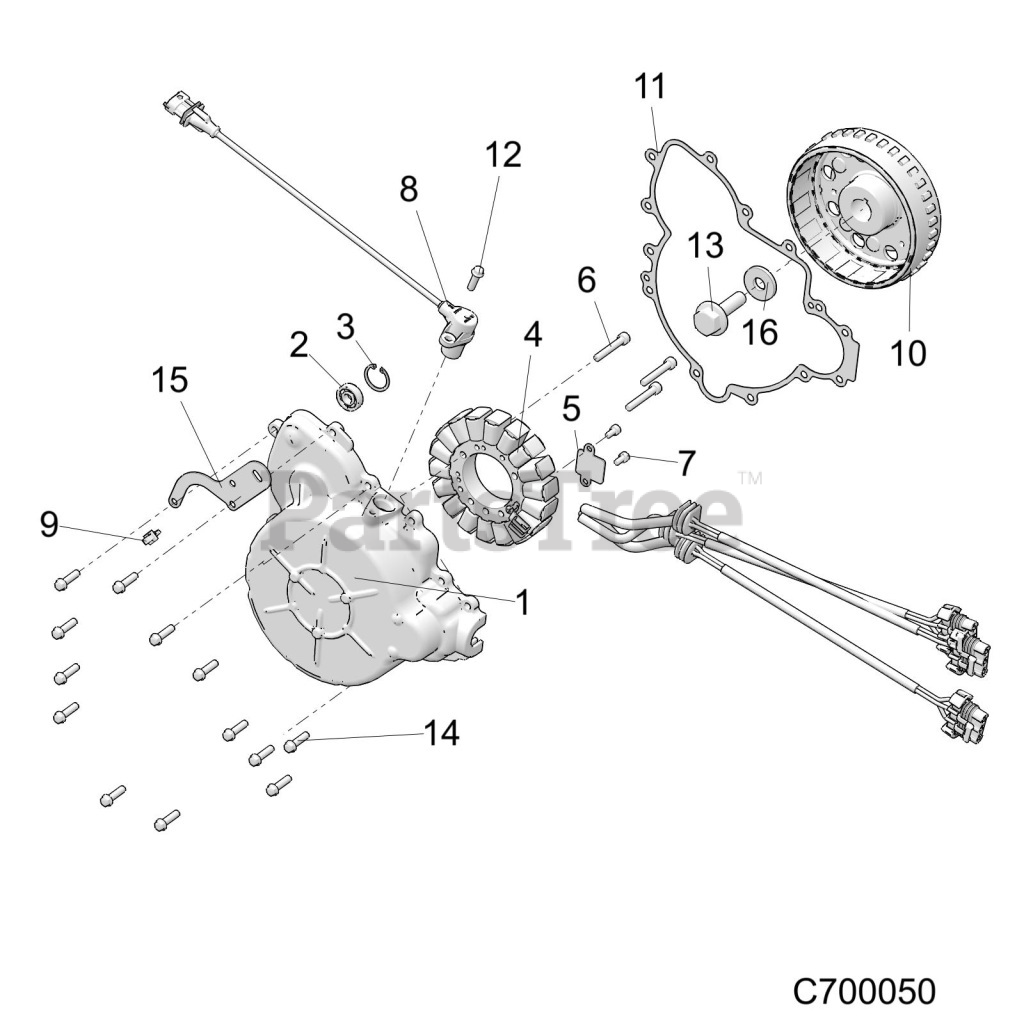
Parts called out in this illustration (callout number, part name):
1	ASM., IGNITION COVER
2	BEARING, BALL
3	RING, SNAP
4	STATOR-900W DUAL,706MM
5	BRACKET, RETAINER, WIRE
6	SCR-M6X1.0X40,HX/SOC/CP-Y/D
7	SCR-M5X0.8X10 SOC/CP-D
8	SENSOR-CRANK POSITION
9	CLIP-WIRE,6.35MM
10	FLYWHEEL-900W
11	GASKET, COVER, IGNITION
12	SCR-M6X20,HXFLG,0600214
14	SCR-HXFLG,M6X1.0X25,10.9
15	BRKT-HOSE,BYPASS
